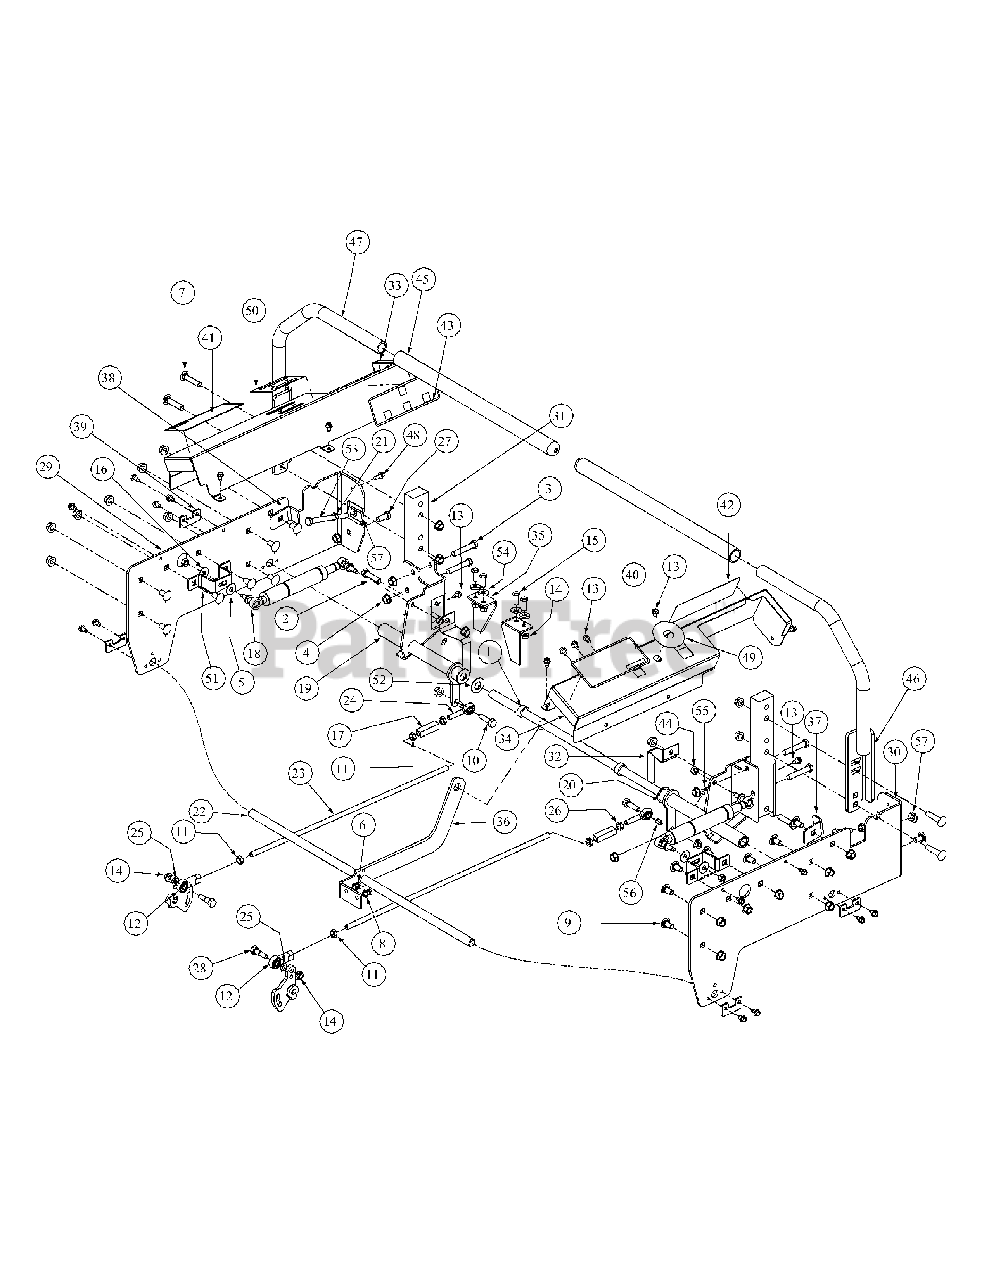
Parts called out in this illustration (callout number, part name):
1	Shaft Collar
2	HHCS, 3/8-16, 2.00
3	HHCS, 3/8-16, 2.25
4	Hex Nut, 3/8-16, Lock Flange
5	External Washer, 3/8
6	HHCS, 1/4-20, .750
7	Hex Carriage Screw, 3/8-16, 1.75
8	Lock Washer, 1/4 Zinc
9	Carriage Bolt, 3/8-16 x .75
10	Capscrew, 3/8-16 x 1-3/4
11	Hex Jam Nut, 3/8-24
12	B/Joint, 3/8-24, Right Hand Female
13	Screw, TT, 1/4-20, 0.5, Hex Index Washer
14	Nut, Lock, Hex Flange, 5/16-18
15	Hex, Cap Screw, 5/16-18 x 3/4
16	Belle Washer, .325 x .930 x .045
17	Turnbuckle
18	Cylinder Return to Neutral
19	Hub Assy, Control LH Bearing
20	Hub Assy, Control RH Bearing
21	Nut, 3/8-16, Jam
22	Shaft Control Brake Steering
23	Rod Connector 3/8 OD x 14.25
24	B/Joint, 3/8-24, Left Hand Female
25	5/16, Lock Washer
26	Nut, 3/8-24, Jam, LH Third
27	HHCS, 5/16-18 x 1.0
28	Screw, Shoulder Control Rod
29	Side Panel, Control, Left
30	Side Panel, Control, Right
31	Mounting Handle
32	Lever, Safety Switch
33	Control Panel, LH
34	Control Panel, RH
35	Switch Mounting Bracket, Lapbar
36	Link Mounting Control Shaft, Bracket
39	Holder Shaft, Park Brake
40	Decal, Right Hand Console
41	Decal, Left Hand Console
42	Decal Right Hand Control
43	Decal, Left Hand Control
44	Nut, Hex, Center Lock, M8
45	Grip, 1.0
46	Lapbar, Weldment, Right Handle
47	Lapbar, Weldment, Left Handle
48	Screw, TT, 1/4-20, 0.75, Hex Index Washer
49	Label, Ignition, 2.5 Diameter
50	Label, Control, Throttle and Choke
51	Bracket Assembly, Mount Dampener
52	Flat Washer, 5/8 Nylon
53	HHCS, 3/8-16, 3.00
54	Flat Washer, 5/16
55	Grease Fitting, 90°.
56	Spacer, .385ID x .625 OD x 50 Lg
57	U-Nut, 3/8-16, .75
